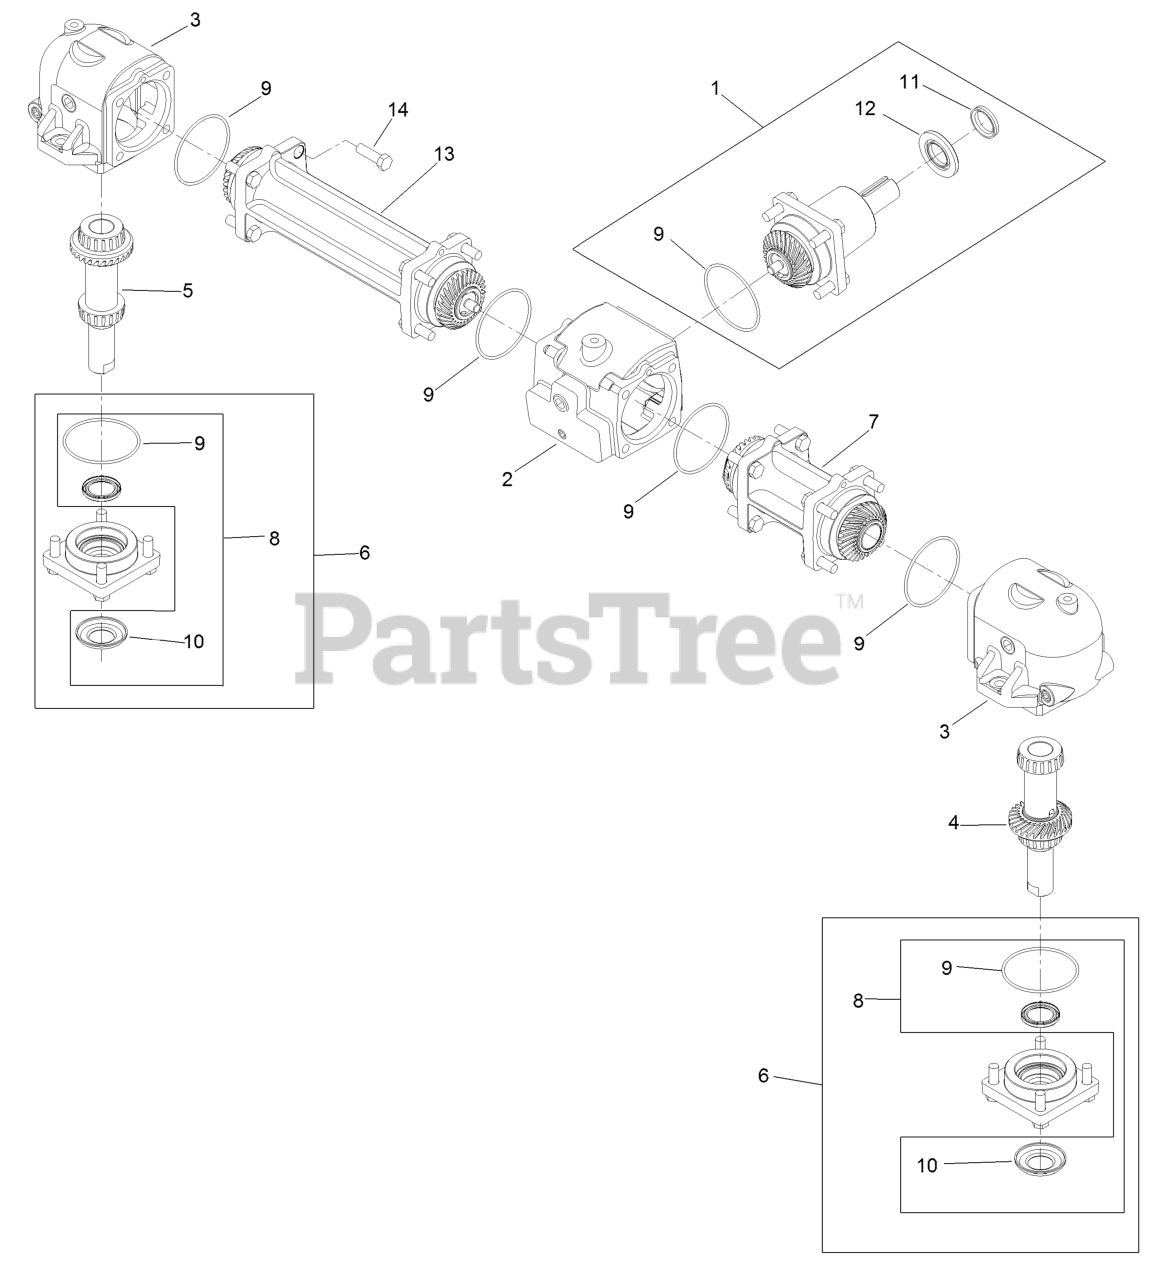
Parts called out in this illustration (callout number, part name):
1	PINION-INPUT
2	HOUSING-CENTER
3	HOUSING-END
4	OUTPUT SHAFT AND GEAR-LH
5	OUTPUT SHAFT AND GEAR-RH
6	CAP-OUTPUT
7	TUBE-CONNECTOR, SHORT
8	OUTPUT SEAL KIT
9	SEAL-O-RING
10	WASHER-CUPPED
11	SEAL-V-RING
12	SEAL-INPUT
13	CONNECTOR-TUBE, LONG
